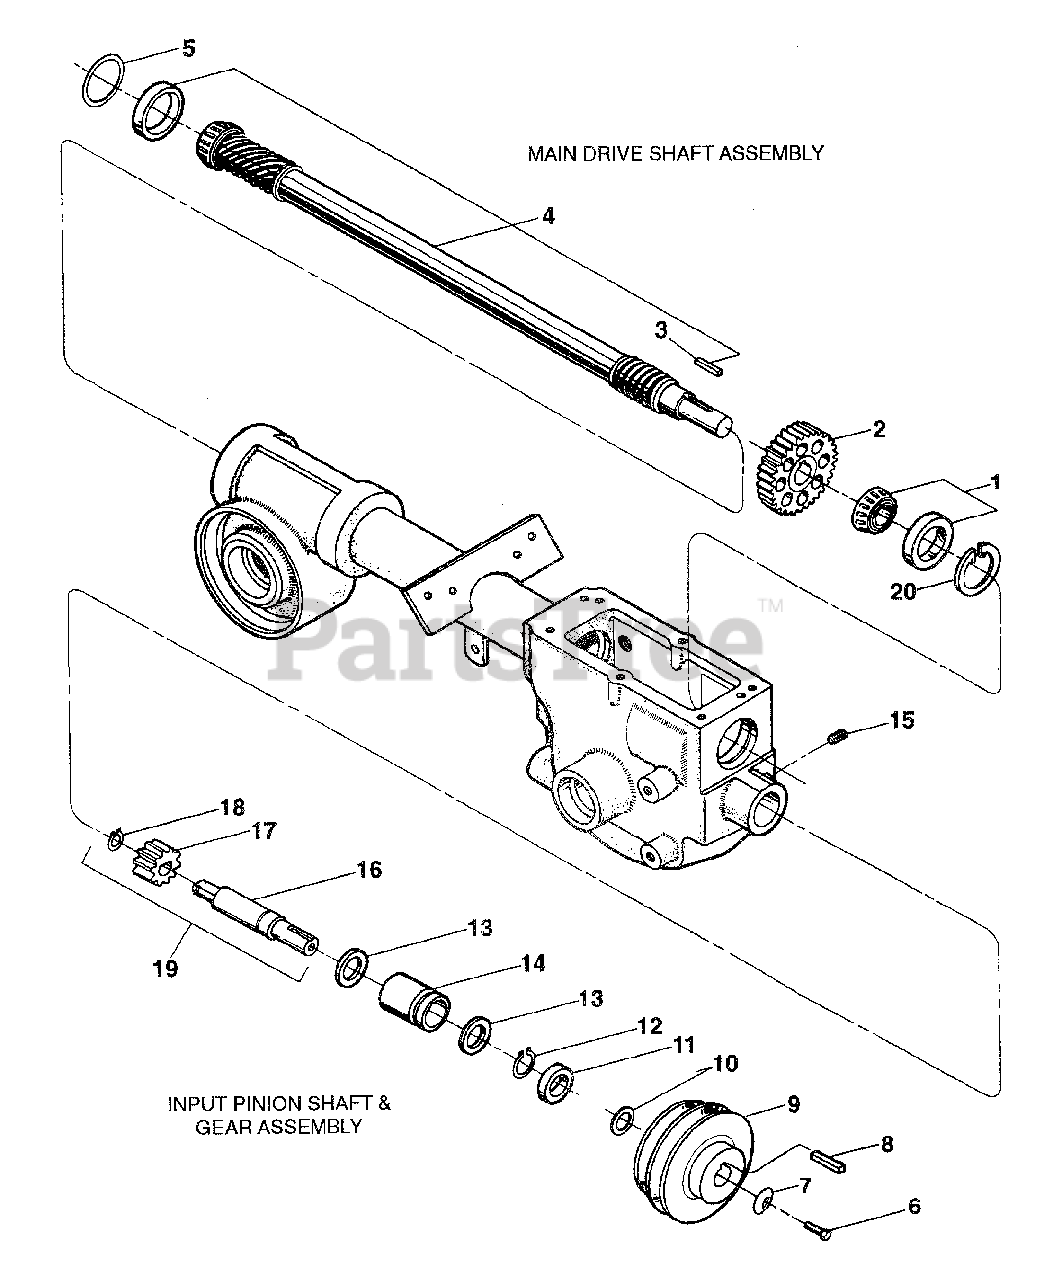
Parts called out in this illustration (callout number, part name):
1	Bearing-tapered roller with race
2	Gear-spur, main drive shaft
3	Key-3/16 sq. x 1
4	Drive Shaft
5	Shim-rear bearing cap, .010 thick
5	Shim-same as above, but .030 thick
5	Shim-same as above, but .005 thick
6	Screw-hex hd., 5/16-24 x 1-1/8
7	Washer-disc spring (concave surface faces pulley)
8	Key-3/16 sq. x 1-1/2
9	Pulley-transmission drive
10	Washer-support
11	Oil Seal-input pinion shaft, front.
12	Ring-retaining (snap ring), external
13	Washer-thrust
14	Bushing
15	Set Screw-5/16-18 x 3/8
16	Input Pinion-steel shaft
17	Gear-input pinion
18	Retainer-snap ring, external
19	Pinion Assy-
20	Retainer-snap ring, internal
